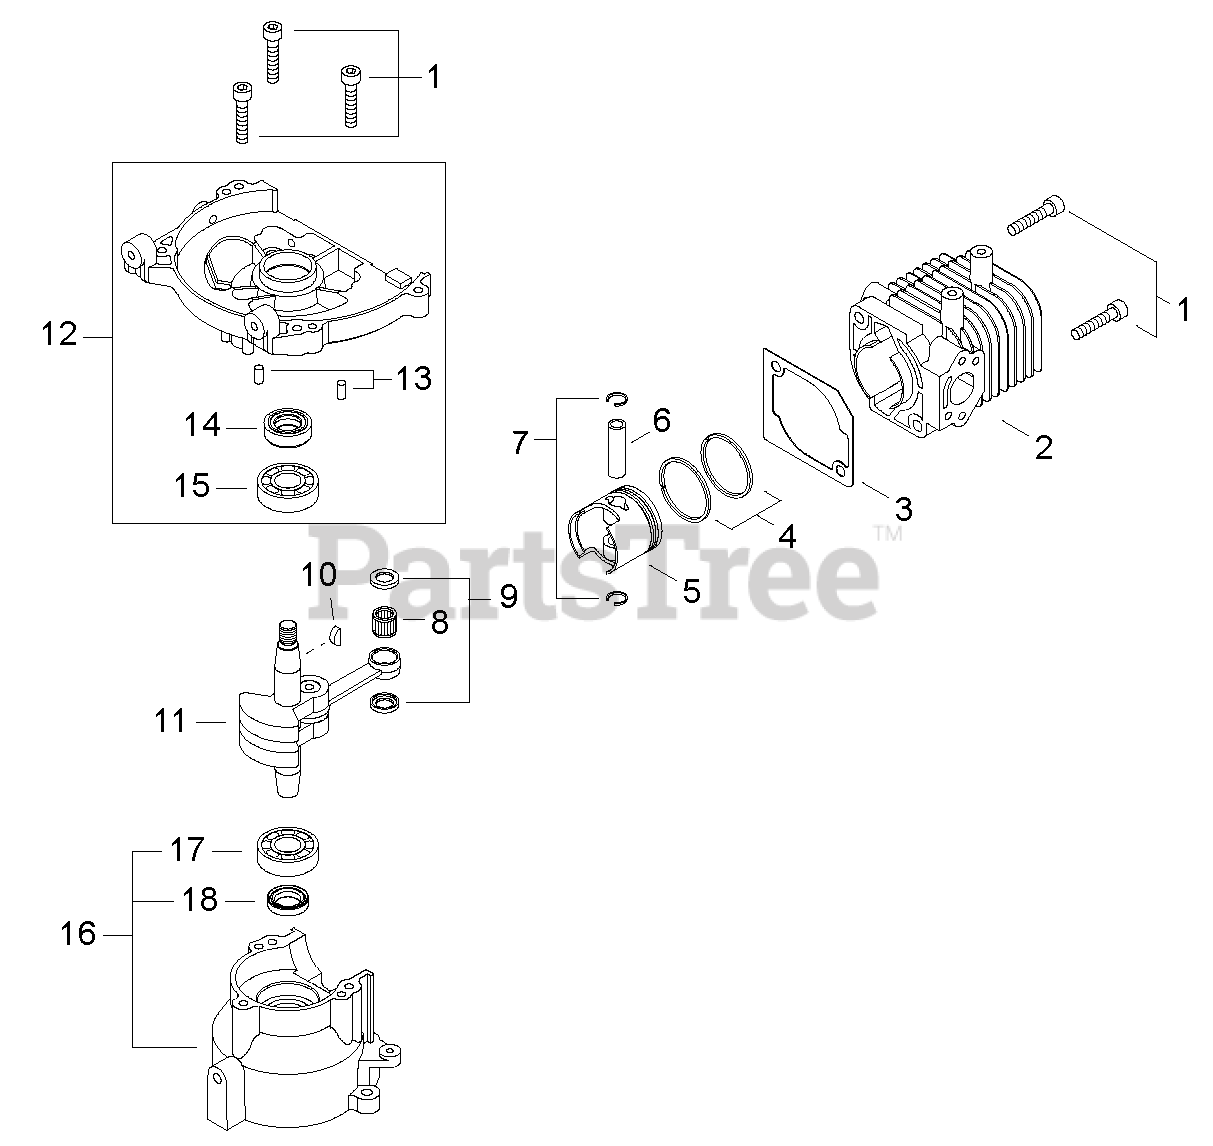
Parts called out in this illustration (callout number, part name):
1	BOLT 5×25
2	CYLINDER
3	GASKET, CYLINDER
4	RING, PISTON
6	PIN, PISTON 8
7	RING, SNAP
8	BEARING, NEEDLE 8
9	WASHER, THRUST 8
10	KEY, WOODRUFF 3×10
11	CRANKSHAFT ASSY
12	CRANKCASE ASSY, M
13	PIN, LOCATING Ø4×8
14	SEAL, OIL 12
15	BEARING, BALL 6001 C3
16	CRANKCASE ASSY, PTO
17	BEARING, BALL 6001 C3
18	SEAL, OIL 12
